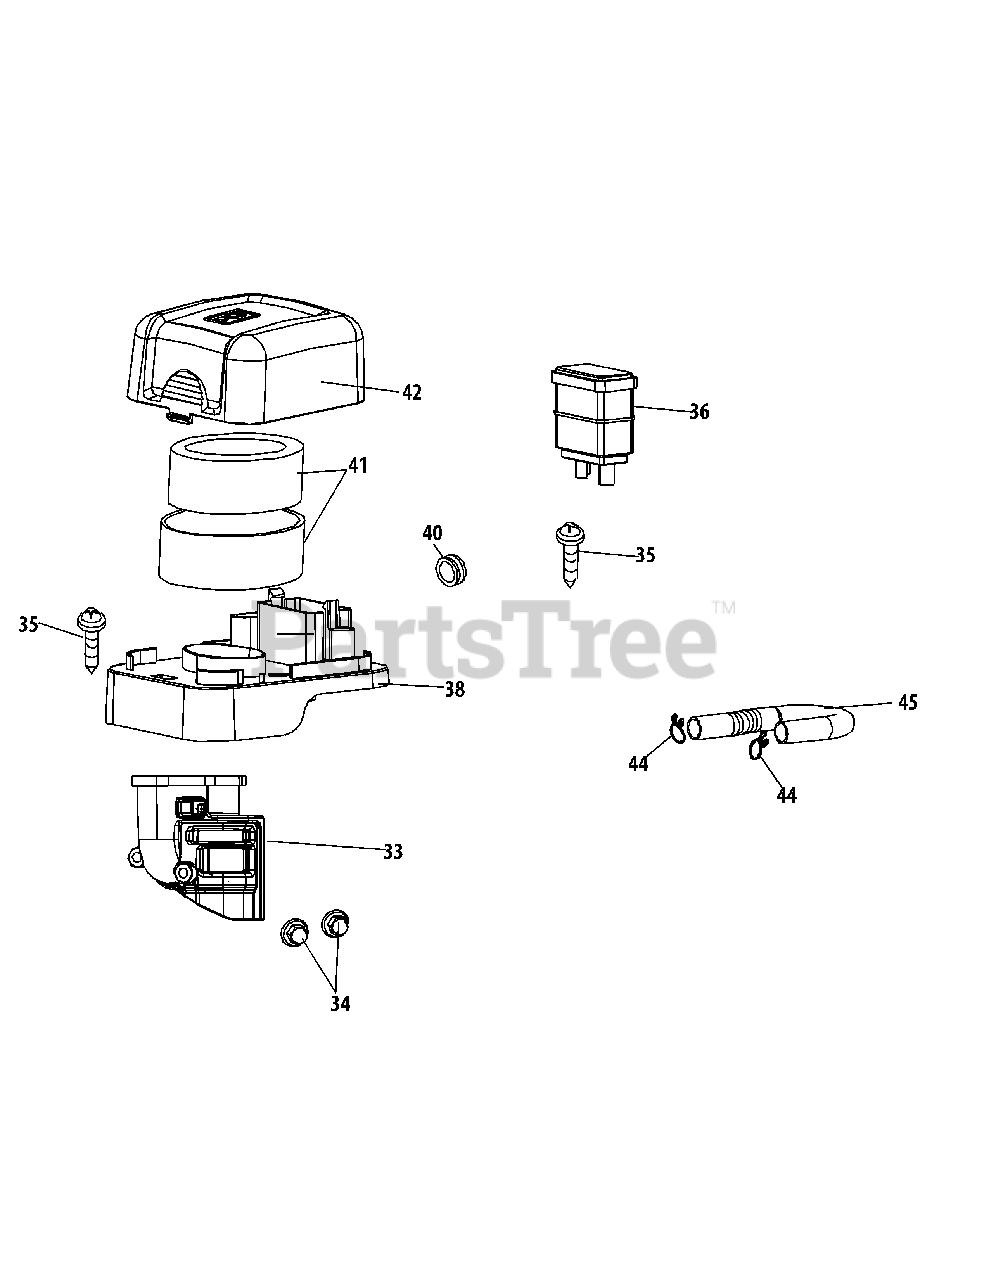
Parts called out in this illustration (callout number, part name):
33	Air Cleaner Housing
35	Self-Tapping Bolt4.2×16
36	Carbon Canister
38	Silencer Plate
40	Damper Gasket
41	Air Filter Element
42	AIR FILTER COVER
45	Exhaust Piping
